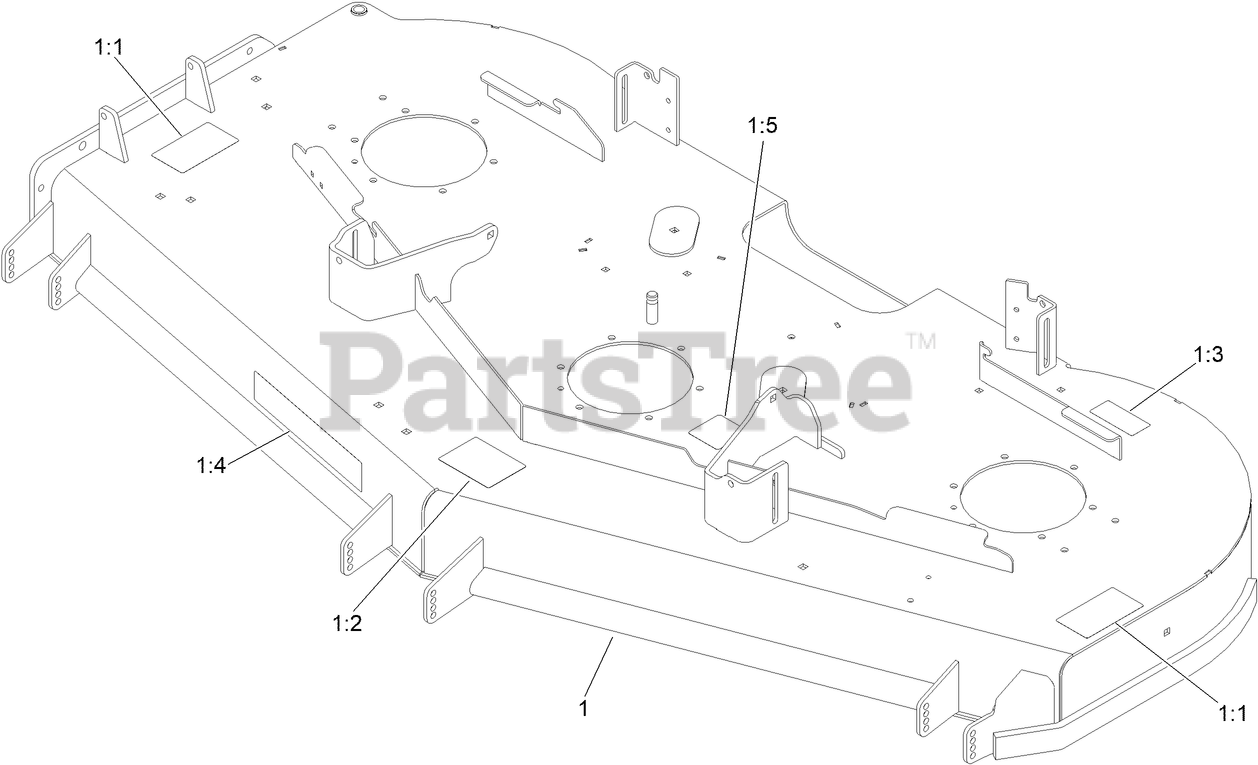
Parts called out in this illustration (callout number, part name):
1	DECK ASM
1:1	DECAL-DANGER
1:2	DECAL-SCALP, ANTI
1:3	DECAL-BOLT TORQUE
1:5	DECAL-ROUTING, BELT
